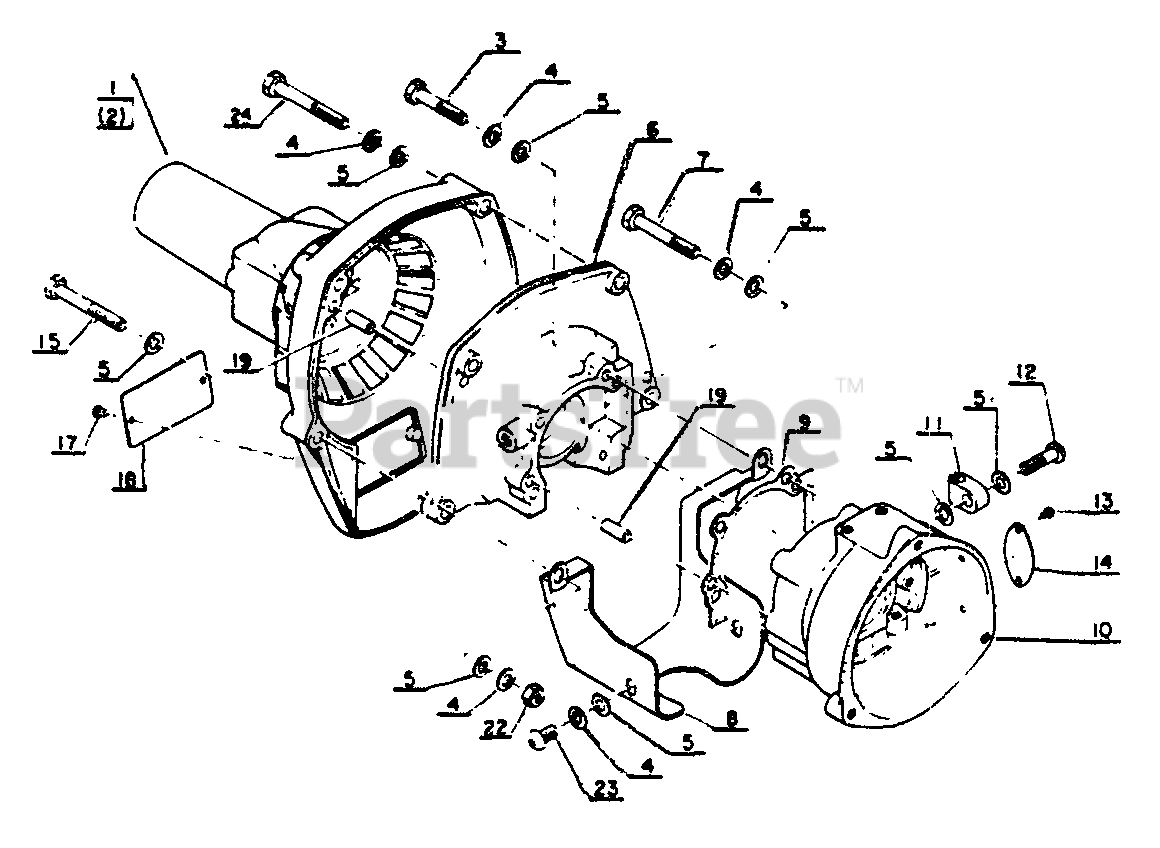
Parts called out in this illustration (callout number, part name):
1	CASE, FAN
3	BOLT, CRANKCASE (A)
4	LOCKWASHER - 5
5	WASHER - 5
6	CRANKCASE - FRONT
7	BOLT, CRANKCASE (B)
8	SHIELD, CYLINDER
9	GASKET, CRANKCASE
10	CRANKCASE - REAR
12	SCREW - 5X18
14	PLATE, MODEL
15	BOLT - 5X40
17	RIVET
18	NAME PLATE
19	PIN - LOCATING
23	SCREW - 5X10
24	BOLT - 5X14
